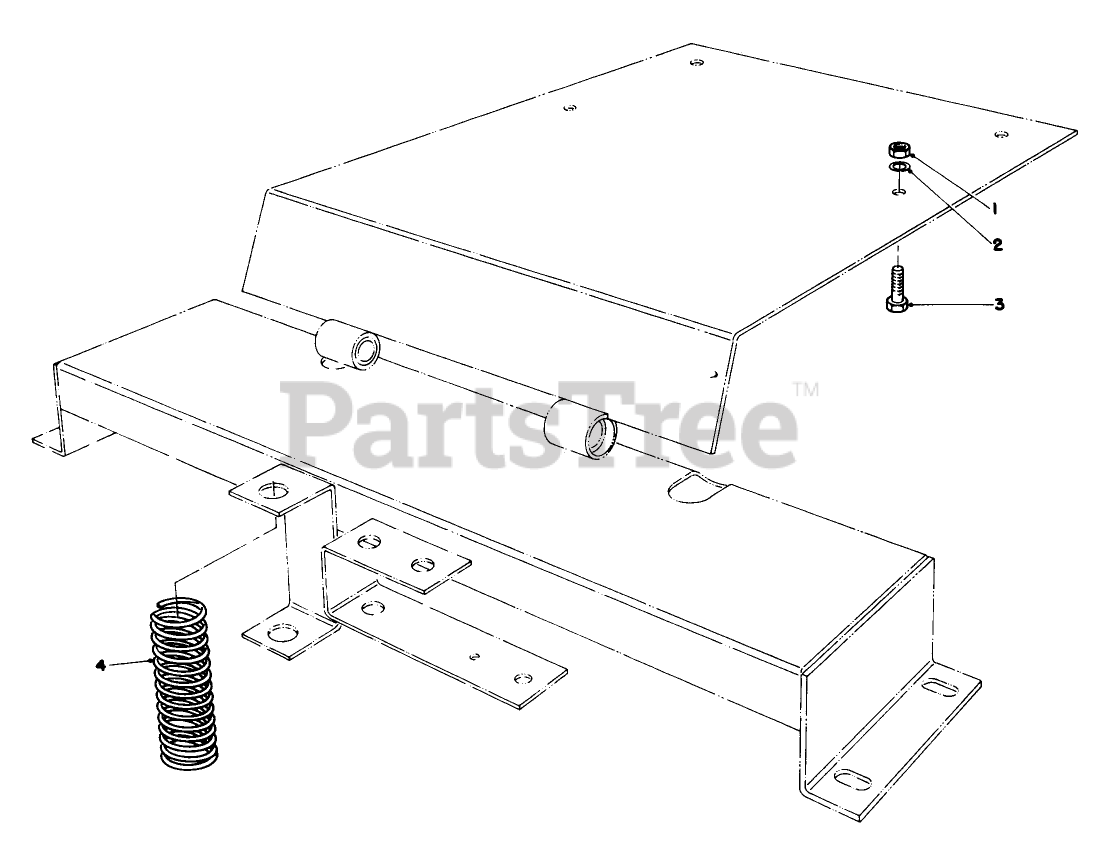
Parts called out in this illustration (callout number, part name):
1	NUT-HEX
2	WASHER-LOCK/SP
3	SCREW-HH
4	COMP SPRING
